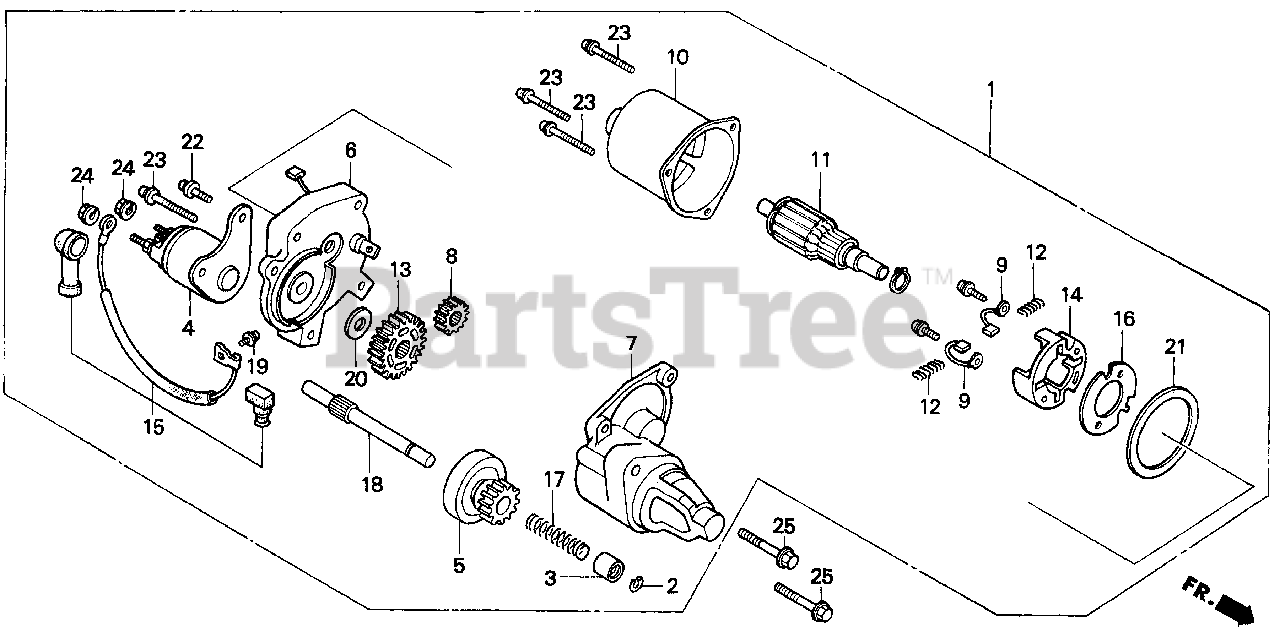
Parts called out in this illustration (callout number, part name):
1	MOTOR ASSY., STARTER
2	RING, SNAP
3	COLLAR, CLUTCH
4	CONTACTOR ASSY.
5	CLUTCH, OVERRUNNING
6	BRACKET, CENTER
7	BRACKET, FR.
8	GEAR, DRIVE PINION
9	BRUSH
10	YOKE
11	ARMATURE
12	SPRING, BRUSH RETURN
13	GEAR, REDUCTION
14	HOLDER, BRUSH
15	WIRE, WATER COVER
16	INSULATOR
17	SPRING
18	SHAFT
19	SCREW-WASHER (4X6)
20	WASHER
21	GASKET
22	BOLT-WASHER (5X14)
22	SCREW-WASHER (5X14)
23	SCREW-WASHER (5X3)
24	NUT-WASHER (6MM)
25	BOLT, FLANGE (8X40)
